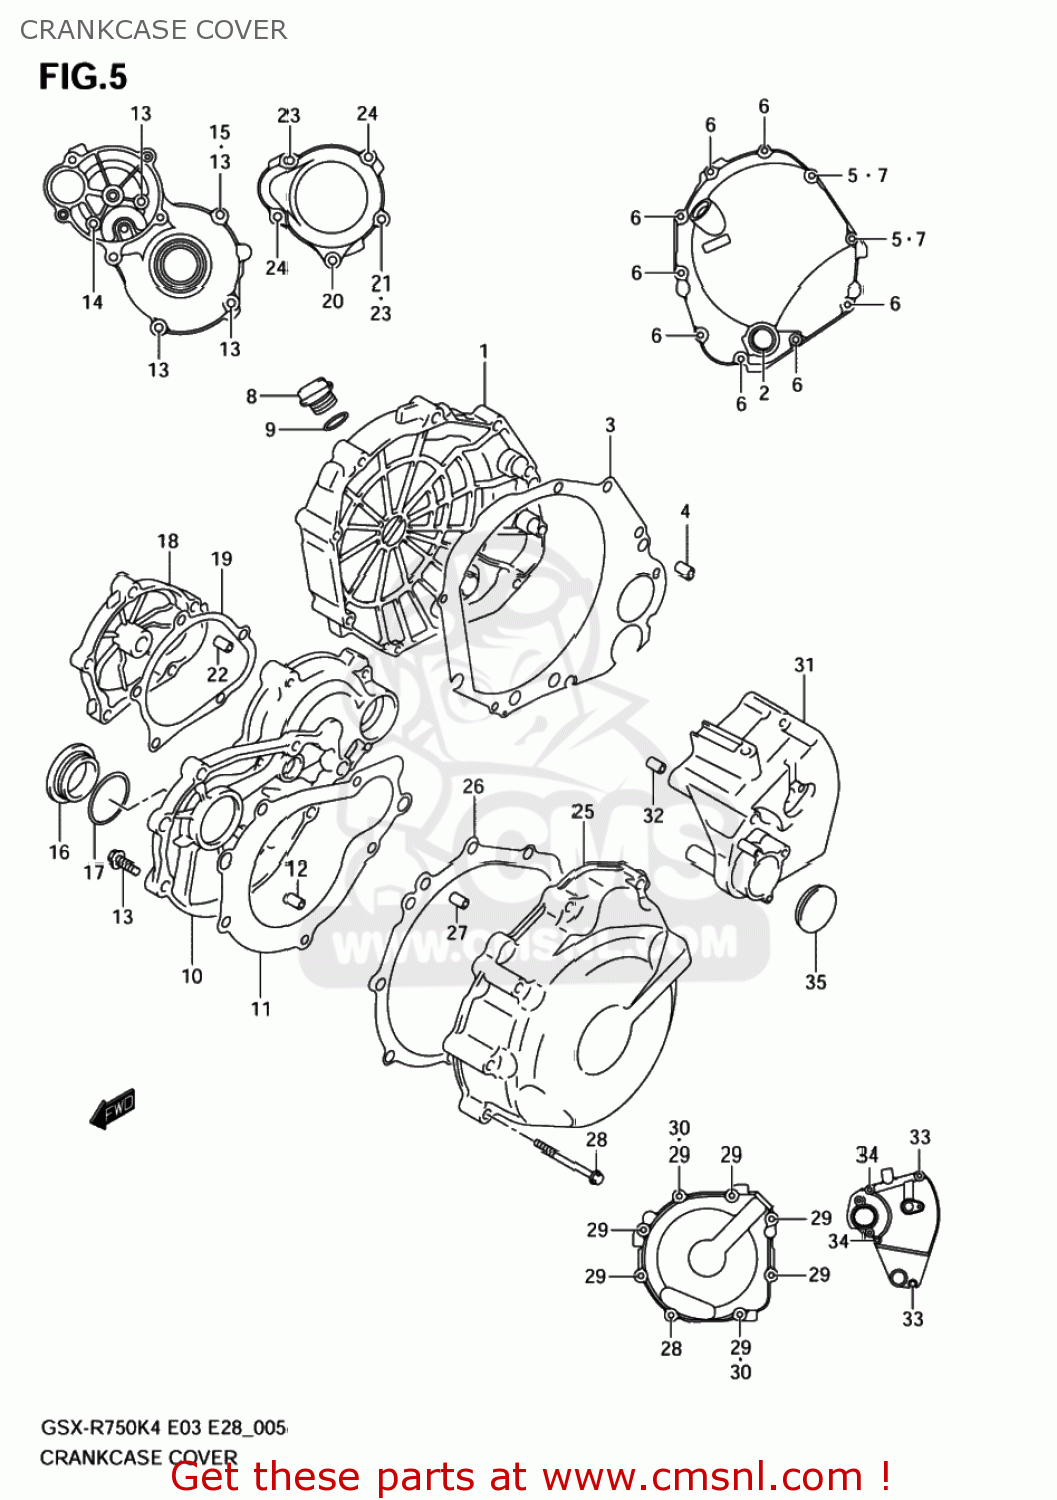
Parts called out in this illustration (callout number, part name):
1	COVER,CLUTCH
2	LENS,OIL LEVEL CHECK
3	GASKET,CL COVE (NAS)
4	PIN
5	GASKET(5.8X13X1.2) (NAS)
6	BOLT,G/S SWITC
7	BOLT
8	PLUG,ENGINE OIL FILLER
9	O RING(D:3.1,ID:16.8)
10	COVER,STARTER CLUTCH
11	GASKET,STARTER CLUTCH COVER
12	PIN
13	SCREW
14	BOLT
15	GASKET(5.8X13X1.2) (NAS)
16	PLUG
17	O RING(D:3.1,ID:32.7)
18	CAP,STARTER IDLE GEAR
19	GASKET,START IDLE GEAR CAP (NAS)
20	BOLT
21	GASKET(5.8X13X1.2) (NAS)
22	PIN
23	SCREW
24	BOLT
25	COVER,MAGNETO
26	GASKET,MAGNETO COVER (NAS)
27	PIN
28	BOLT,G/S SWITC
29	BOLT
30	GASKET(5.8X13X1.2) (NAS)
31	COVER,ENGINE SPROCKET
32	PIN
33	BOLT
34	BOLT
35	CAP(OD:36)
